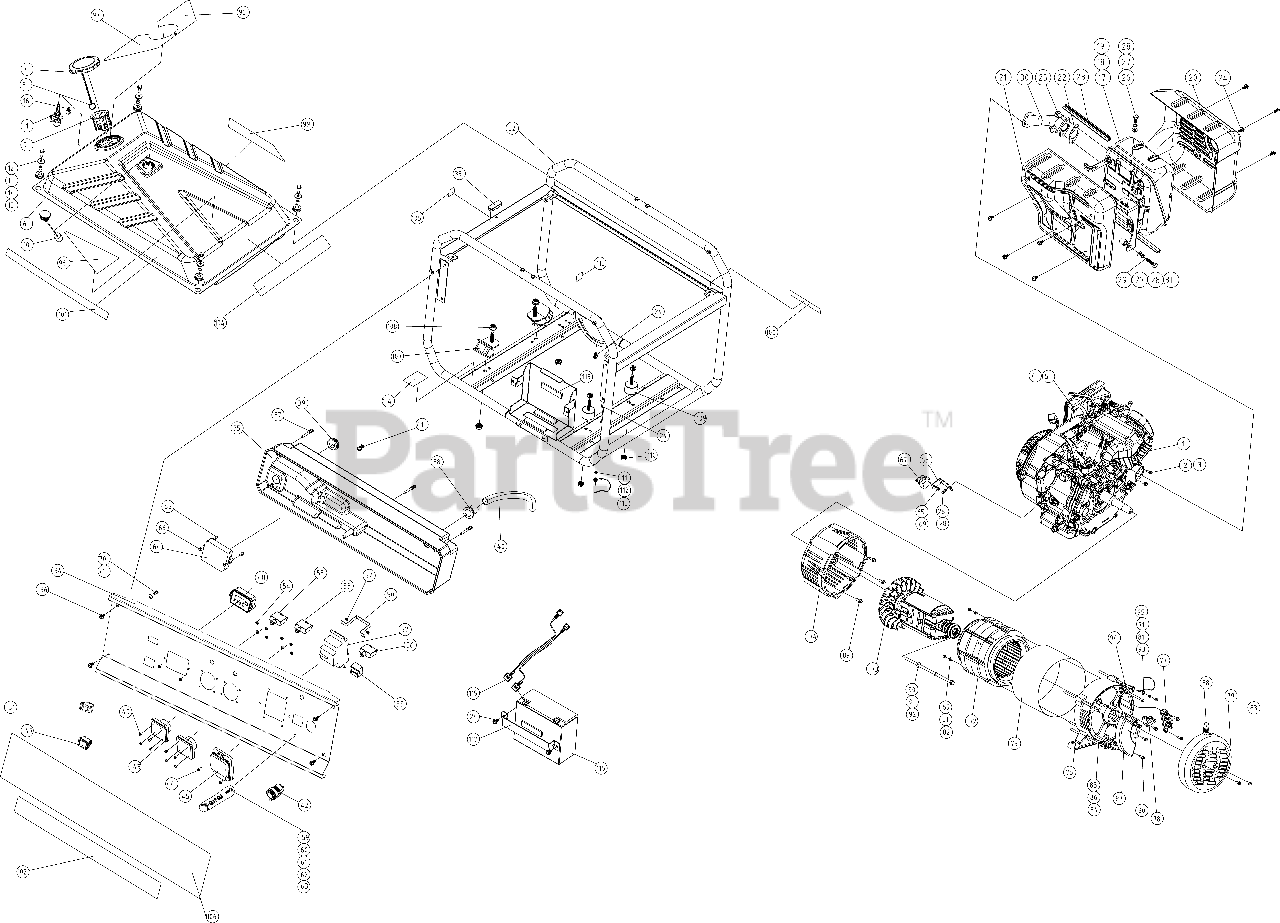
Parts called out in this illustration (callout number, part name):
2	GASKET, EXHAUST PIPE
3	NUT USE 25 086 240-S
4	FUEL HOSE, LOW PERMEATION
5	CLAMP, FUEL LINE 1 USE 14 237 01-S
6	TANK, FUEL
7	CAP ASSEMBLY - FUEL TANK (EPA)
8	RETAINER, TANK CAP PULL RING
9	FILTER , FUEL TANK
10	GUAGE, FUEL LEVEL ASSEMBLY
11	VALVE,FUEL SHUT OFF
12	SCREW, BOLT GB 5787-M6X20
13	MOUNT, FLAT GASKET GB/T 5287-6
14	SPACER, FUEL TANK BUSHING
15	SPACER, INNER RING
16	CLAMP, FUEL LINE 6
20	COVER, MUFFLER FRONT
21	COVER, MUFFLER BACK
23	MOUNT, RUBBER GASKET
24	SCREW, BOLT M6X12
25	SCREW, BOLT M8X22
26	SCREW, BOLT M8X20
27	WASHER, FLAT GASKET 8
28	WASHER, SPRING 8
29	SCREW, BOLT L35
31	SPACER, MUFFLER BUSHING
33	DAMPER, HANDLE DAMPING PAD
35	ELECTRIC BOX
36	SCREW, BOLT GB5789-M6X12
37	SCREW M5X45
38	GROMMET, POWER CORD SHEATH
39	GROMMET 16MM
41	STRAP, CABLE TIES 3.2X120 (WHITE)
44	SCREW M4X12
45	Socket Cover(RCD)
56	BREAKER, CIRCUIT 10A
59	SCREW, BOLT M6X25
61	WASHER, PLATE GASKET 6
62	WASHER, SPRING GASKET 6
64	MODULD, IDLE CONTROL
65	SCREW M5X16-GB818
67	RECTIFIER, BLOCK (PRO5.2E)
68	BRACKET, STATIONARY BARRIER
70	SCREW M5X12
71	WASHER, SPRING GB 93-5
73	ROTOR ASSEMBLY (PRO7.5E)
76	CAP, BACK COVER
77	BOARD ASSEMBLY, PATCH
78	BRUSH, CARBON ASSEMBLY
79	FAN COVER
80	SCREW, BOLT GB 5787-M5X16
81	WASHER, PLATE GT/T 95
82	SCREW, BOLT M5X205
83	SCREW, BOLT M5X10
84	BOLDT M6X220
85	WASHER, PLATE GASKET 6
86	WASHER, SPECIAL SPRING 6
87	RECTIFIER AVR (PRO7.5E)
88	SLEEVE, MOTOR RUBBER SHEATH
89	SCREW BOLT 3/8-16X27MM
90	BOLT 5/16-24X261MM
92	WASHER, SPRING
93	BOLT GB/T 5783-M5X10
94	RETAINER, 12V DC CHARGE BRIDGE
96	DECAL, TANK BRAND, LEFT
100	SAFETY DECAL
101	CPSC DECAL_5.2
102	DECAL, OPERATE
104	DECAL, GENERATOR_WARNING
105	FUEL SWITCH DECAL
107	MOUNT, ENGINE ISO
109	MOUNT, RUBBER FOOT
111	GROUND WIRE
112	SPACER, FLOWER SHAPED GASKET
116	KIT, BATTERY RACK 12V18AH
117	BRACKET, BATTERY
118	DAMPER - DAMPING STRIP
119	HARNESS ASSEMBLY, WIRING
